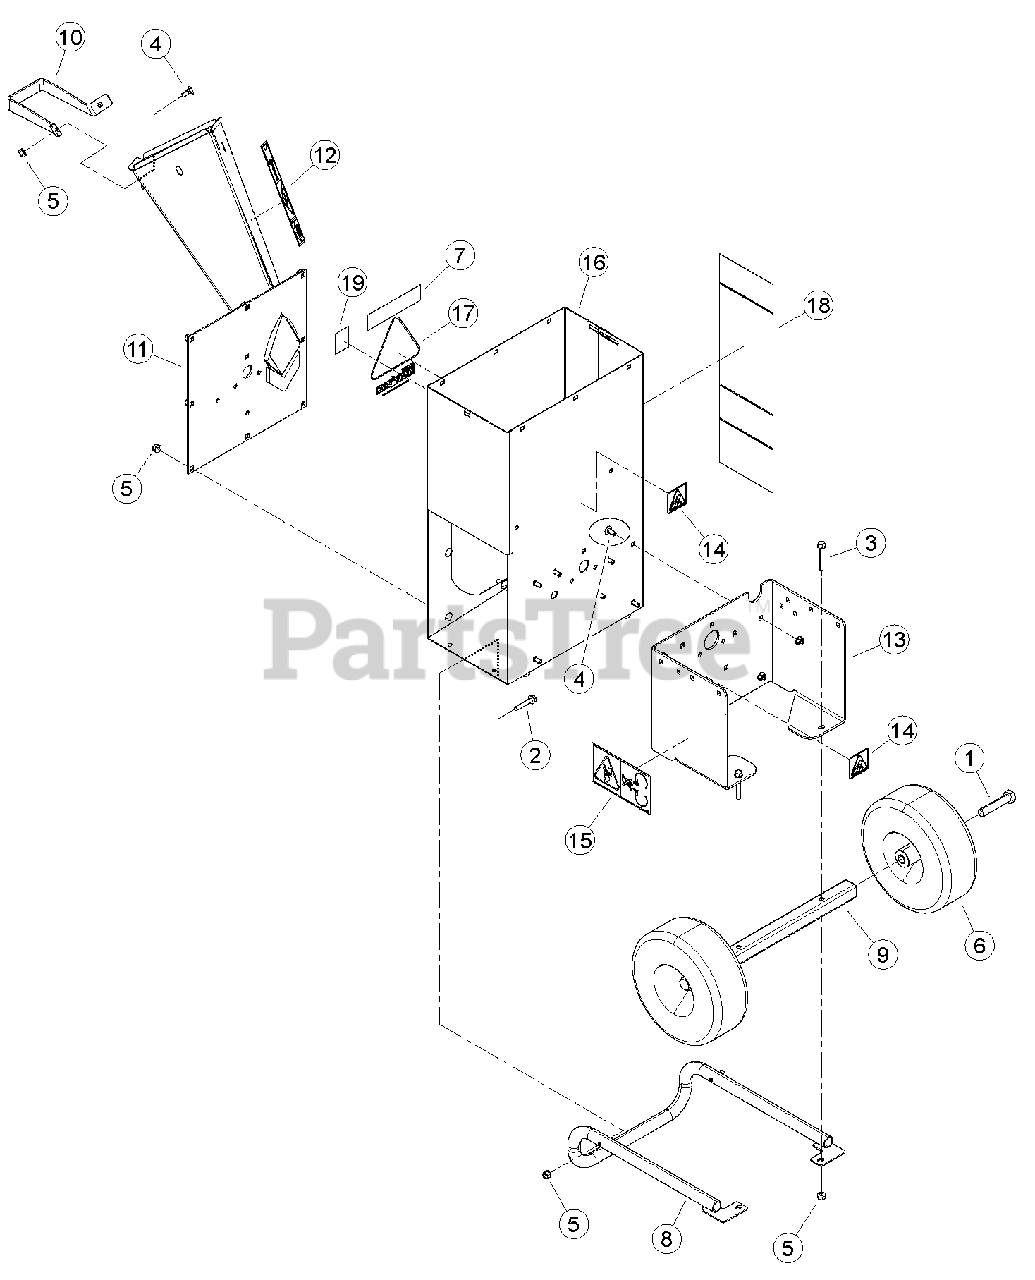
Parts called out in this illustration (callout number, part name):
1	BOLT, 5/8 X 3 HEX HD GR5 ZP
2	BOLT, 5/16 X 1-3/4 FLANGE NC
3	BOLT, 5/16 X 2-1/4 FLANGE NC
4	BOLT, 5/16 X 3/4 GR5 CRG NC ZP
5	NUT, 5/16-18 NYLOCK FLANGE
6	ASSEMBLY, 410/350-4 FLAT-FREE WHEEL
7	DECAL, MODEL SC3306
8	WELDMENT, SUPPORT LEG LONG
9	WELDMENT, AXLE 3 IN CHIPPER
10	HANDLE, CHIPPER CHUTE 3 IN
11	ASSEMBLY, 3 IN FRONT PLATE COMP
12	DECAL, 3" CHIPPER CHUTE
13	ASSEMBLY, BASE 3 IN CHIPPER SERVICE
14	DECAL, SHIELD DANGER ISO
15	DECAL, BLADE DANGER ISO
16	ASSEMBLY, 3" C/S WIDE BODY SERVICE
17	DECAL, SHRED IT
18	DECAL, 3" CHIPPER BODY SIDE
19	DECAL, ECHO BEARCAT QR CODE
